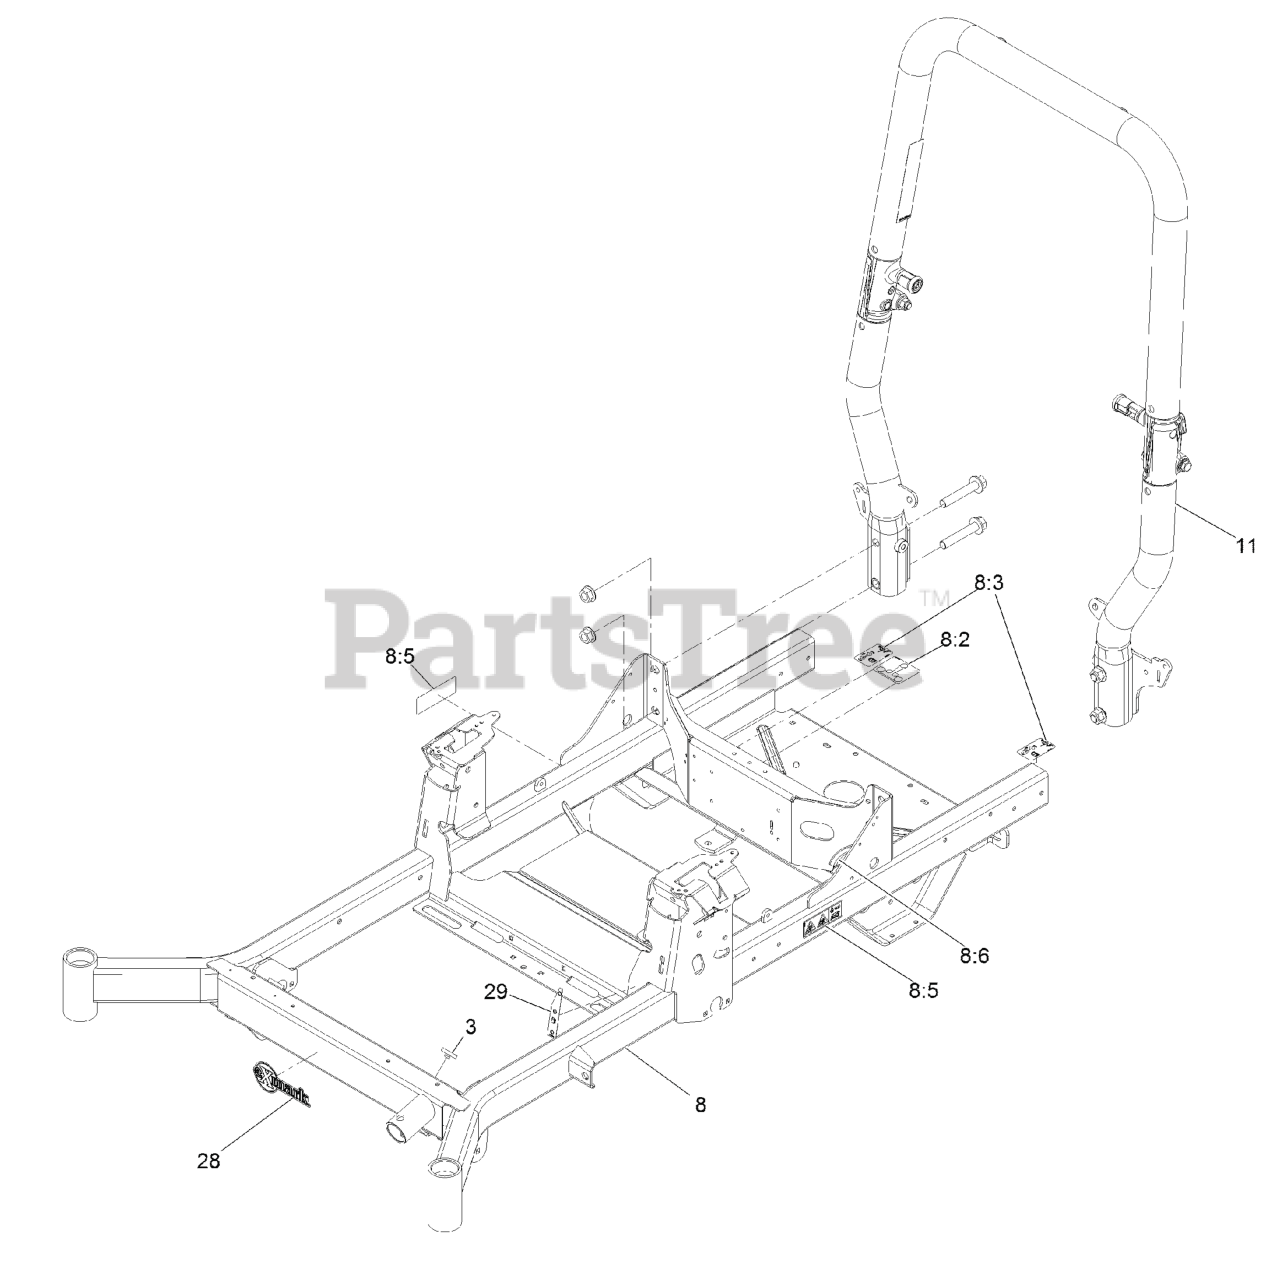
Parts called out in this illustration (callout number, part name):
3	BUMPER-PUSH-IN, RUBBER
8	Frame-60, Suspension
8:2	DECAL-ROUTING, BELT
8:3	DECAL-RELEASE, DRIVE
8:5	DECAL-WARNING
8:6	STRIP-SEAL
11	ASM-ROPS TAPERED
28	DECAL-EXMARK LOGO
29	DECAL-FILL, FUEL
